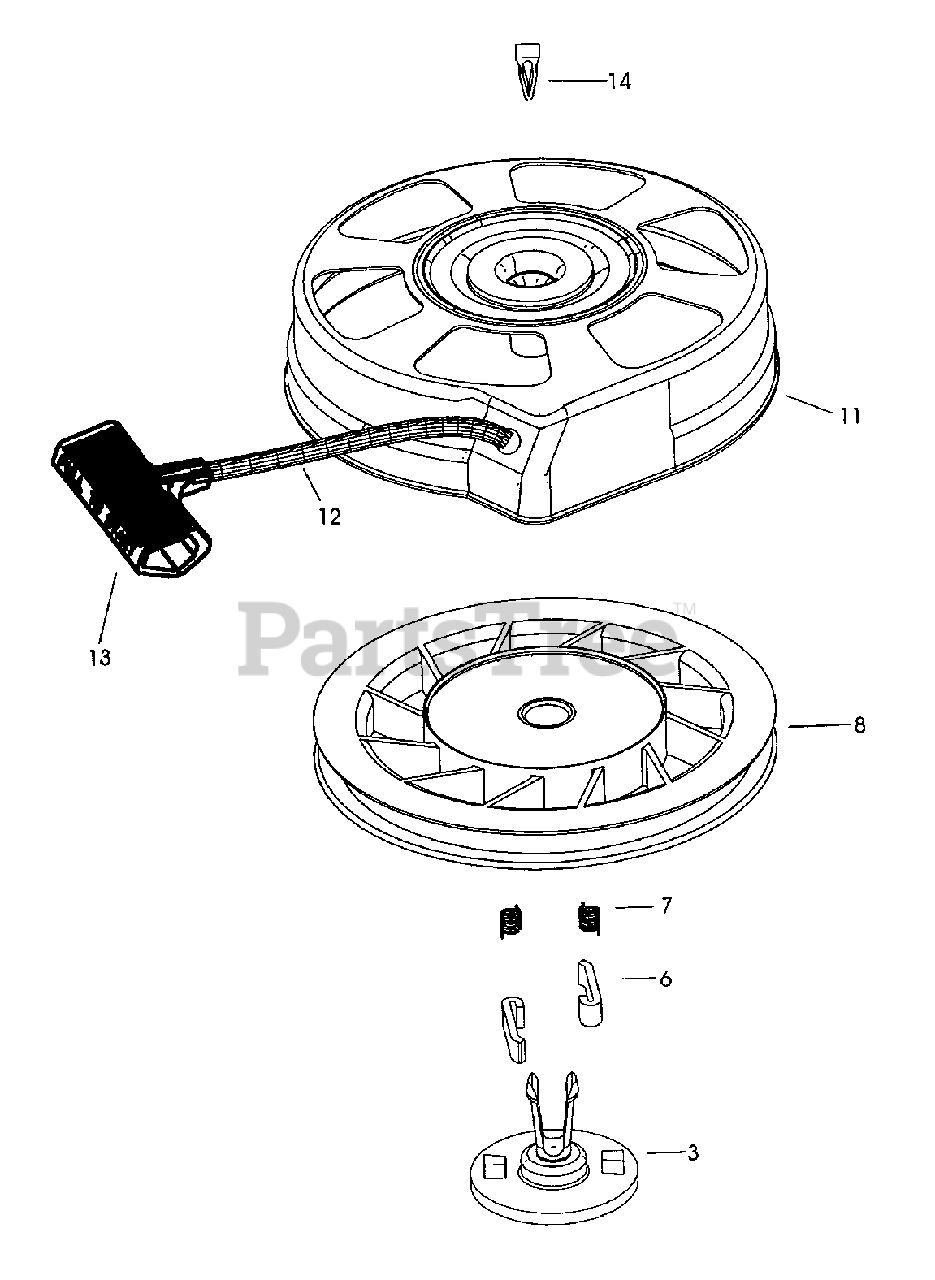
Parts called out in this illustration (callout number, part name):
3	Retainer
6	Starter Dog
7	Dog Spring
8	Pulley & Rewind Spring Ass'y
11	Starter Housing Ass'y (40 degree grommet)
12	Starter Rope (Length 98" x 9/64" dia.)
13	Starter Handle
14	Locking Tab
